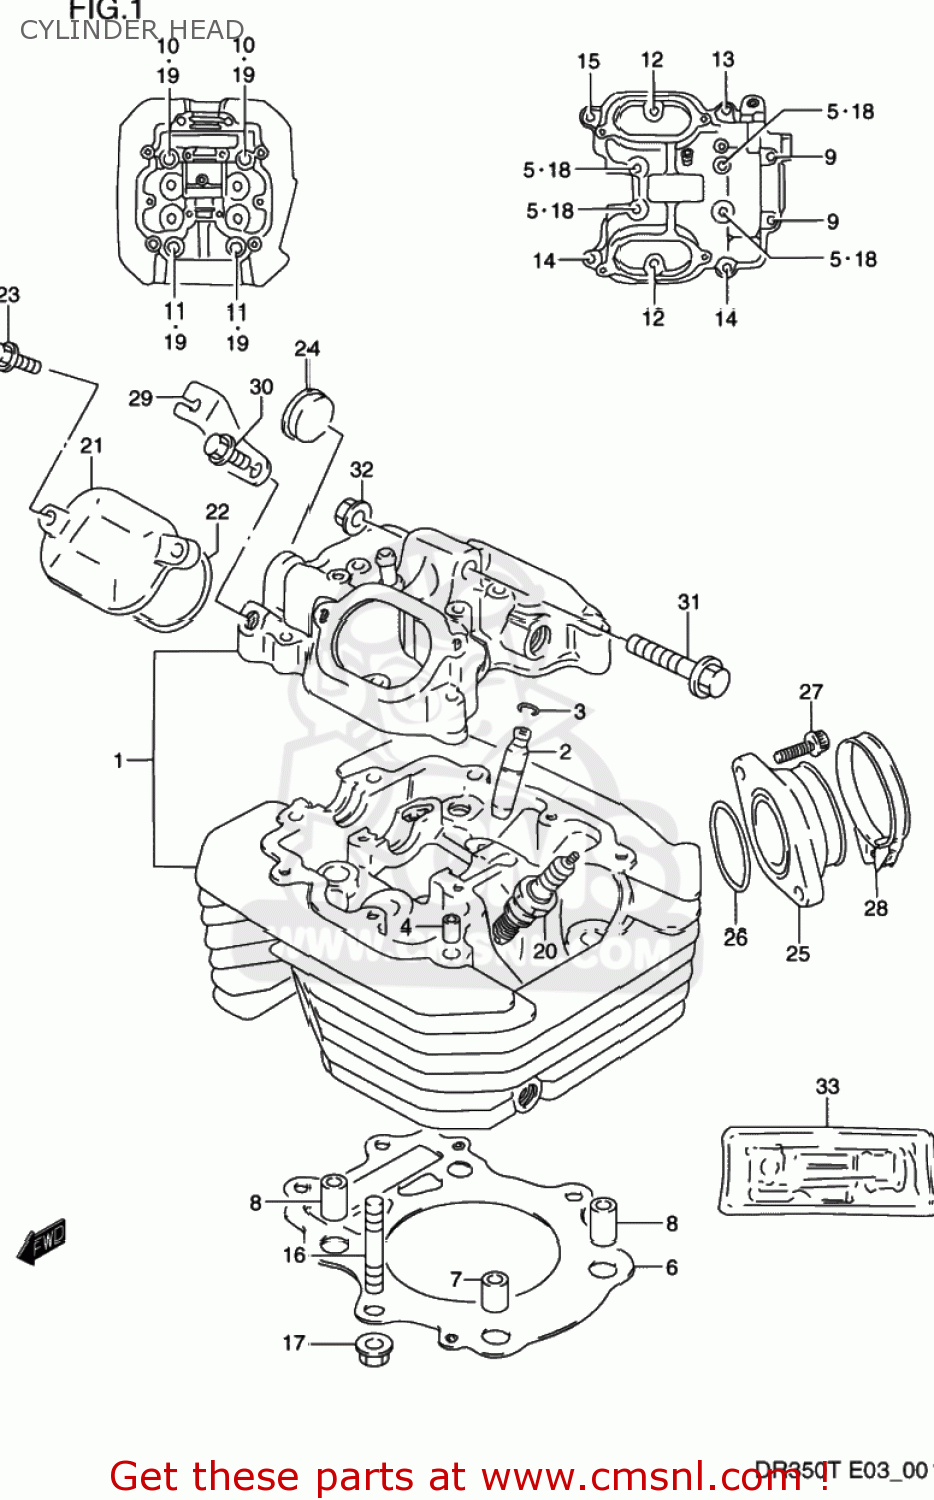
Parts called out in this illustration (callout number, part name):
1	HEAD ASSEMBLY,CYLINDER
2	GUIDE,VALVE
3	RING,SNAP
4	PIN(6.2X8X11)
5	BOLT(6X55)
6	GASKET,CYLINDER HEAD (NAS)
7	PIN
8	PIN(10.4X13X22)
9	BOLT(6X115)
10	BOLT(10X180)
11	BOLT(10X155)
12	BOLT
13	BOLT
14	BOLT(6X35)
15	BOLT(6X39)
16	BOLT,STUD
17	NUT
18	GASKET(5.8X13X1.2) (NAS)
19	WASHER (10.5X22X2.3)
20	PLUG,SPARK(CR9EK)
21	CAP,INSPECTION
22	GASKET (NAS)
23	BOLT
24	PLUG,OD:30
25	PIPE ASSEMBLY,INTAKE
26	O RING(D:2.4,ID:39.7)
27	BOLT
28	CLAMP
29	LEVER,DECOMP SHAFT RH
30	BOLT
31	BOLT(8X65)
32	NUT
33	GASKET SET (NAS)
